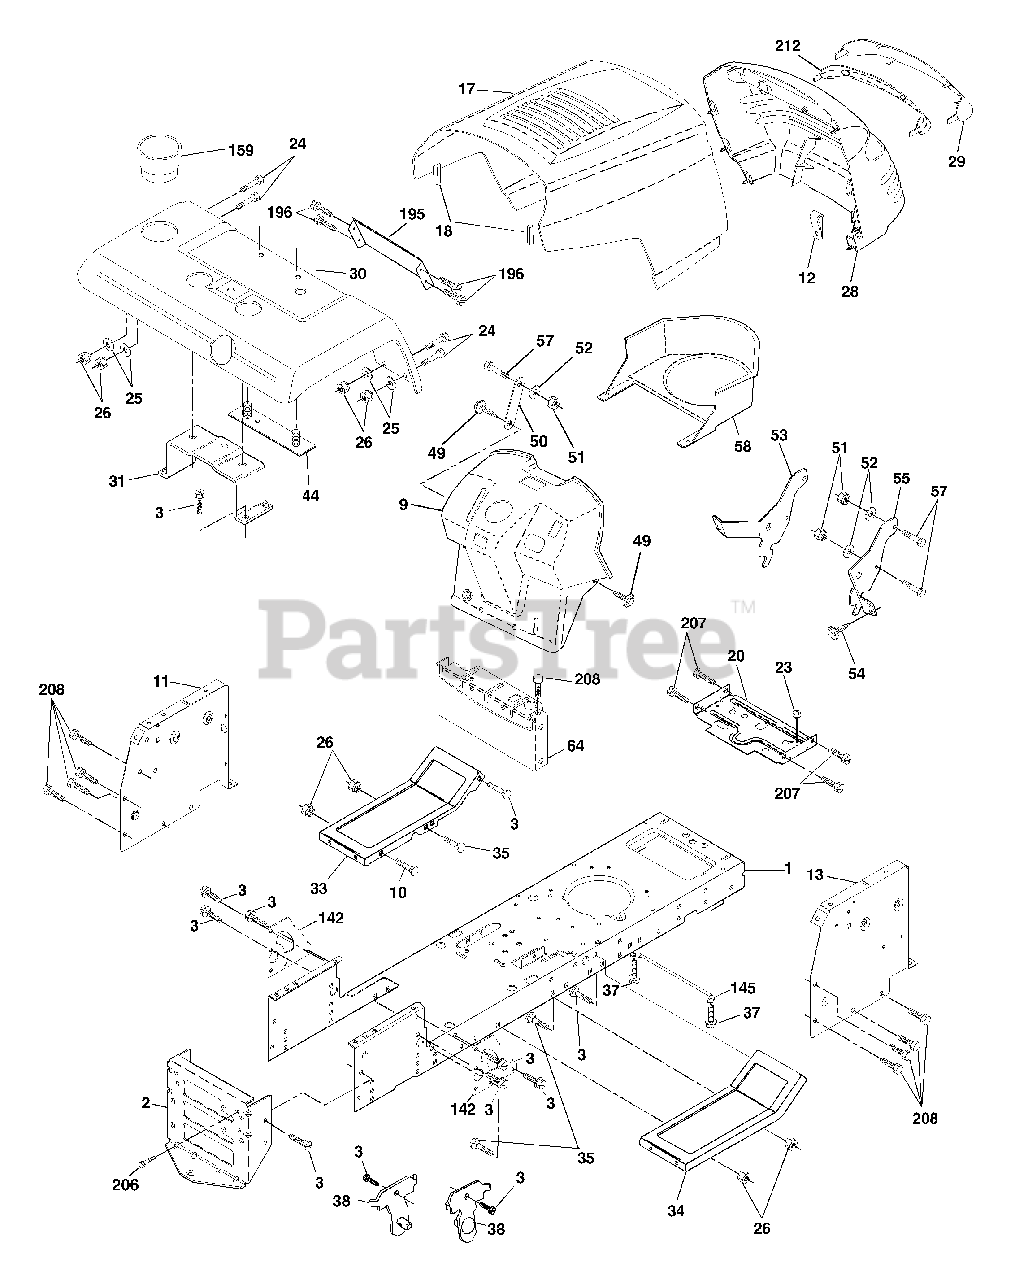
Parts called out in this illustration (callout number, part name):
1	Chassis
2	Drawbar
3	Screw 3/8-16x3/4
10	Bolt Carriage 3/8-16 x 1
11	Panel Dash Lh
12	Clip Tinnerman
13	Panel Dash Rh
17	Hood LT/PL
18	Bumper Hood
20	Plate Mtg Battery Fuel Tank Fr
23	Bushing
24	Bolt Fin Hex 3/8-16 x 1 Gr 5
25	Washer 13/32 X 13/16 X 12 Ga
26	Nut Lock Hex W/Ins 3/8-16 Unc
28	Grille/Lens Asm.
29	Lens P/L
30	Fender Pnt YTGT w/Shift w/fuel
31	Bracket Fender
33	Footrest Pnt Lh
34	Footrest Pnt Rh
35	Bolt Rdhd Sht Sqnk 3/8-16 x 3/4
37	Screw Thdrol 6/16-18 x 1/2 TYT
38	Bracket, Asm. Pivot Mower Rear
44	Strap Asm Fender
49	Screw Hexwsh Thdrol 1/4-20 x 3/4
50	Brace Support Dash P/L
51	Nut Lock Hex W/Ins 1/4-20
52	Washer 9/32 x 7/8 x 16 Ga.
53	Bracjet Grukke Lh
54	Screw Hex Wshd 8-18 x 7/8
55	Bracket Grille Rh
57	Bolt Hex 1/4-20 x 3/4
58	Duct Air
64	Dash Lower STLT
68	Nut Keps Hex 1/4-20 Unc
142	Plate Reinforcement STLT
159	Cupholder
195	Panel Pnt Fender YT/GT
196	Screw Tap Tite 1/4-20 x 1/2
206	Bolt Shoulder 5/16-18
207	Screw Thdrol 5/16-18 x 1/2
208	Screw Thdrol 3/8-16 x 1/2
212	Insert Lens Reflective
